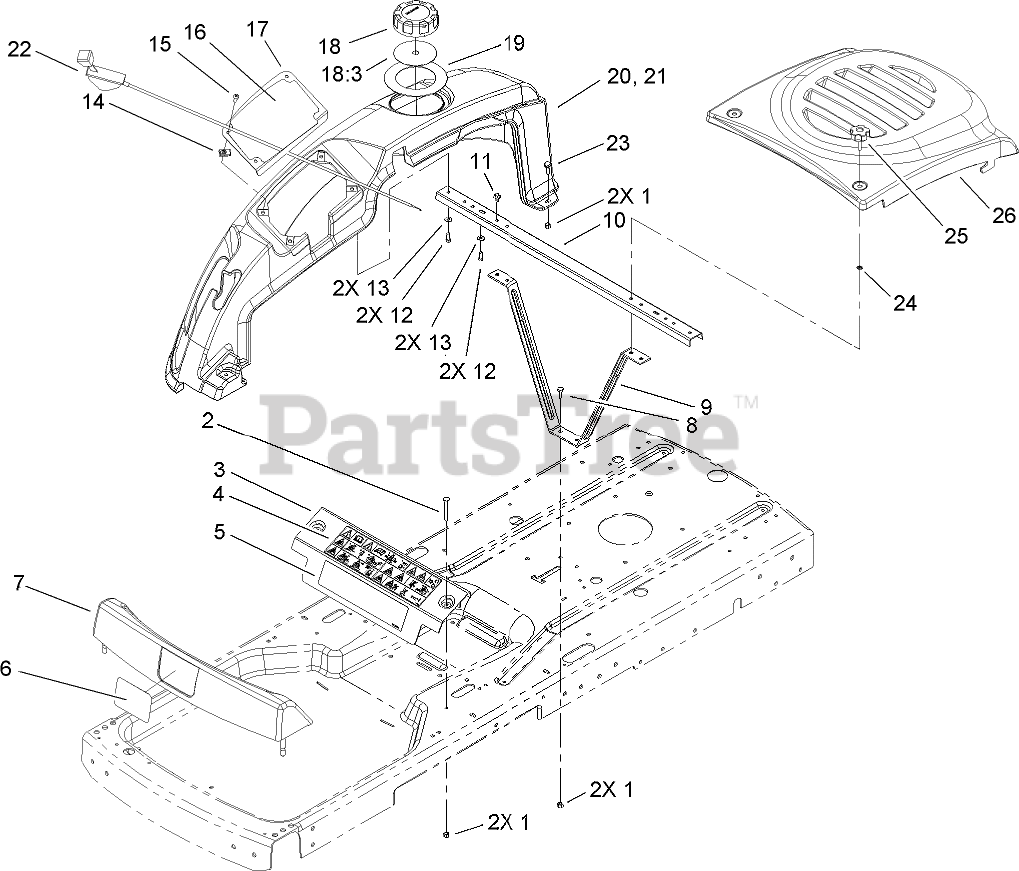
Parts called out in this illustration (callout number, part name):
1	NUT-LOCK, NI
2	SCREW-CARR
3	BRACKET-SUPPORT, FRONT
4	DECAL-DANGER
7	FOOTREST ASM
8	SCREW-HH
9	BRACE ASM
10	CHANNEL-CROSS
11	SCREW-HHFTF
12	SCREW-PLASTITE
13	WASHER-FLAT
15	SCREW-PRH
16	DECAL-CONTROL
17	PANEL-CONTROL
18	GAS CAP ASM
18:3	GASKET-CAP, GAS
19	SEAL-RUBBER
20	COVER-SIDE, RH
22	CABLE-THROTTLE
23	SCREW-SHOULDER
24	NUT-RETAINER
26	COVER-ENGINE
